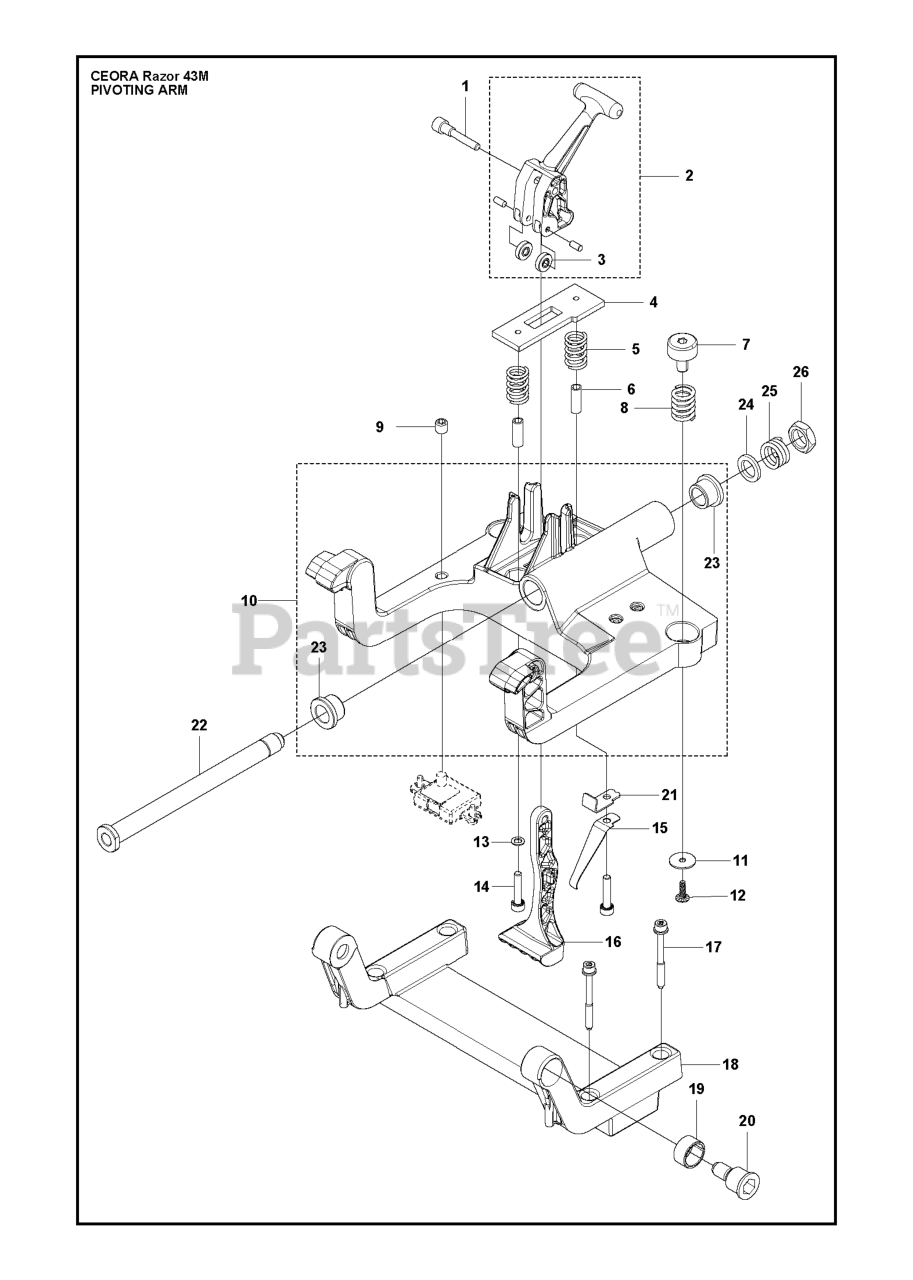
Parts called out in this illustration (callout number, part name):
1	JOINT PIN TO EXCENTER
2	BRACKET LOCKING LEVER ASSY
3	WHEEL
4	PLATE EXCENTER SUPPORT PLATE
5	SPRING EXCENTER PLATE COLOUR
6	SLEEVE EXCENTER PLATE
7	COVER HORIZONTAL DAMPER
8	SPRING HORIZONTAL DAMPER COLOU
9	SCREW IHSETM HEXAGON SOCKET SE
10	BRACKET INTERFACE + BUSHING
11	WASHER 5.5X22X1.5 ST ZPB
12	SCREW ITXPANT
13	WASHER 6.5X11
14	SCREW ITXSCM M6X30 T27 10.9 Z
15	SPRING EXCENTER HOOK
16	HOOK LOCK TO EXCENTER
17	SCREW ISO 10644 M6X60-10.9-S1
18	BRACKET INTERFACE CUTTING UNIT
19	BUSHING PIVOT INTERFACE
20	SCREW
21	SUPPORT SPRING LIMITER
22	SHAFT
23	BUSHING 16X22X16 PLASTIC
24	WASHER ISO 8738 16X24X3 200HV
25	SPRING AXIAL DAMPER
26	HEXAGON THIN NUT
